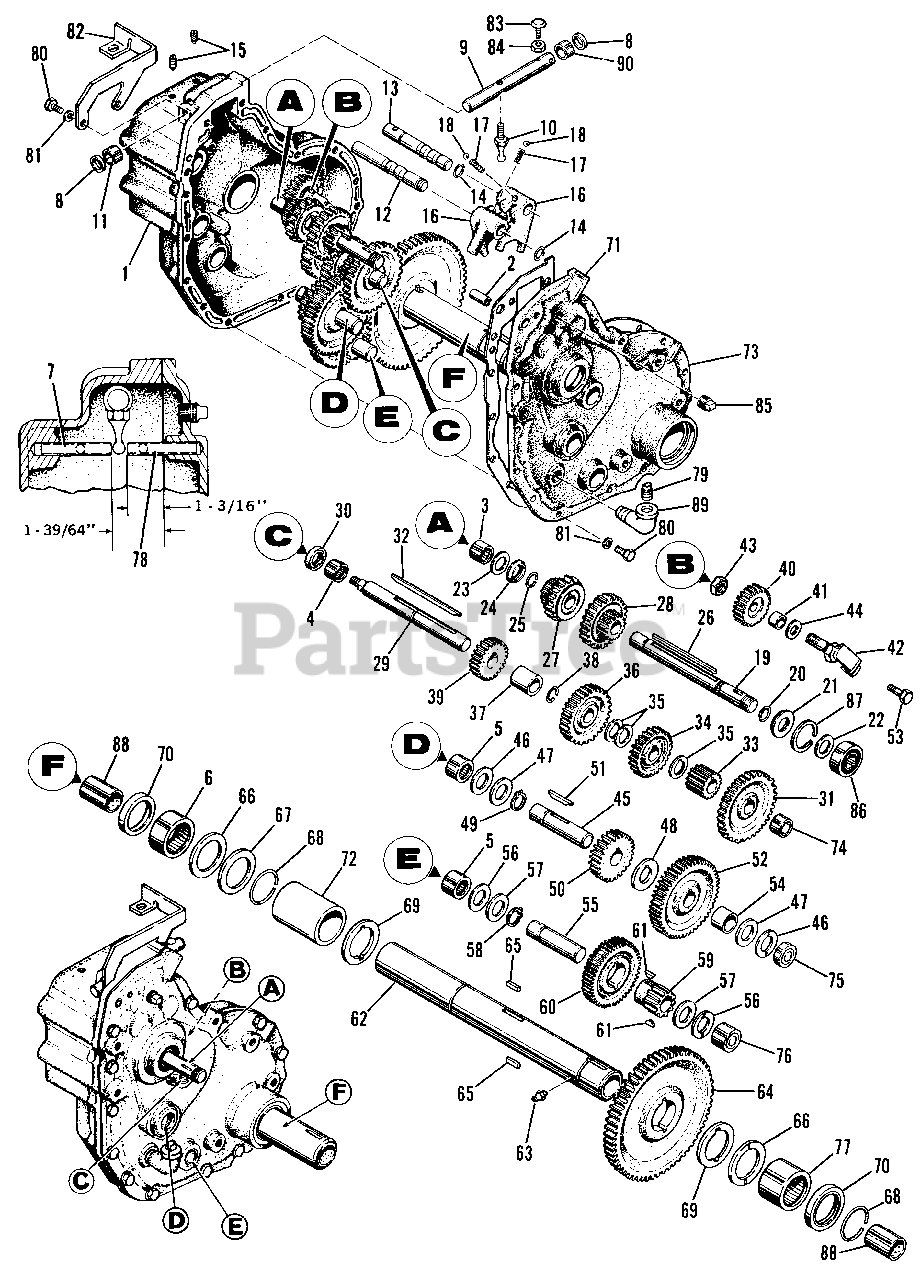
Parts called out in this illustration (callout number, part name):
1	Case, Gear Assy., Complete w/bearings & dowel pins (Includes 1 thru 7)
3	Needle Bearing
4	Needle Bearing
5	Needle Bearing
6	Needle Bearing
9	Shift Rod
12	Shifter Shaft Rev., Med.
13	Shifter Shaft High, Low
14	Retaining Ring
15	Set Screw, Hollow Head, Cone Point, 5/16"-18 x 1/2"
18	Shift Lock Ball
19	Pulley Shaft
20	Retaining Ring
25	Retaining Ring
27	Pinion Assembly Rev. II
28	Pinion Assembly, I and II
29	Shaft, 1st Intm.
31	Driven I, Gear
33	Pinion, 1st Intm.
34	Pinion, Driven, III
36	Driven II Gear
38	Retaining Ring
39	Pinion Rev & IV
40	Reverse Gear
41	Rev. Gear Spacer
42	Rev. Gear Pin Assembly
43	Lock Nut, 1/2"-20 N.F.
45	Shaft, 2nd Intm.
49	Retaining Ring
50	Pinion, 2nd Intm.
52	Gear, 2nd Intm.
53	Hex Capscrew, 3/8"-16 x 1-1/4"
55	Shaft, 3rd Intm.
58	Retaining Ring
59	Pinion, 3rd Intm.
60	Gear, 3rd Intm.
61	Key Woodruff
62	Axle Tube w/bushing
63	Grease Fitting
64	Drive Gear
69	Axle Tube Washer
71	Gear Case Gasket
72	Axle Tube Spacer
73	Gear Case Cover, Complete w/bearings
74	Needle Bearing
75	Needle Bearing
76	Needle Bearing
77	Needle Bearing
78	Roll Pin Assembly
79	Pipe Plug, 3/8"
80	Hex Capscrew, 5/16"-18 x 1"
81	Lockwasher, 5/16"
82	Switch Support
83	Carriage Bolt,5/16"-18 x 1"
84	Hex Jam Nut, 5/16"-18
85	Pipe Plug, 3/8"
86	Ball Bearing
87	Retaining Ring
89	Elbow, 3/8" x 90
